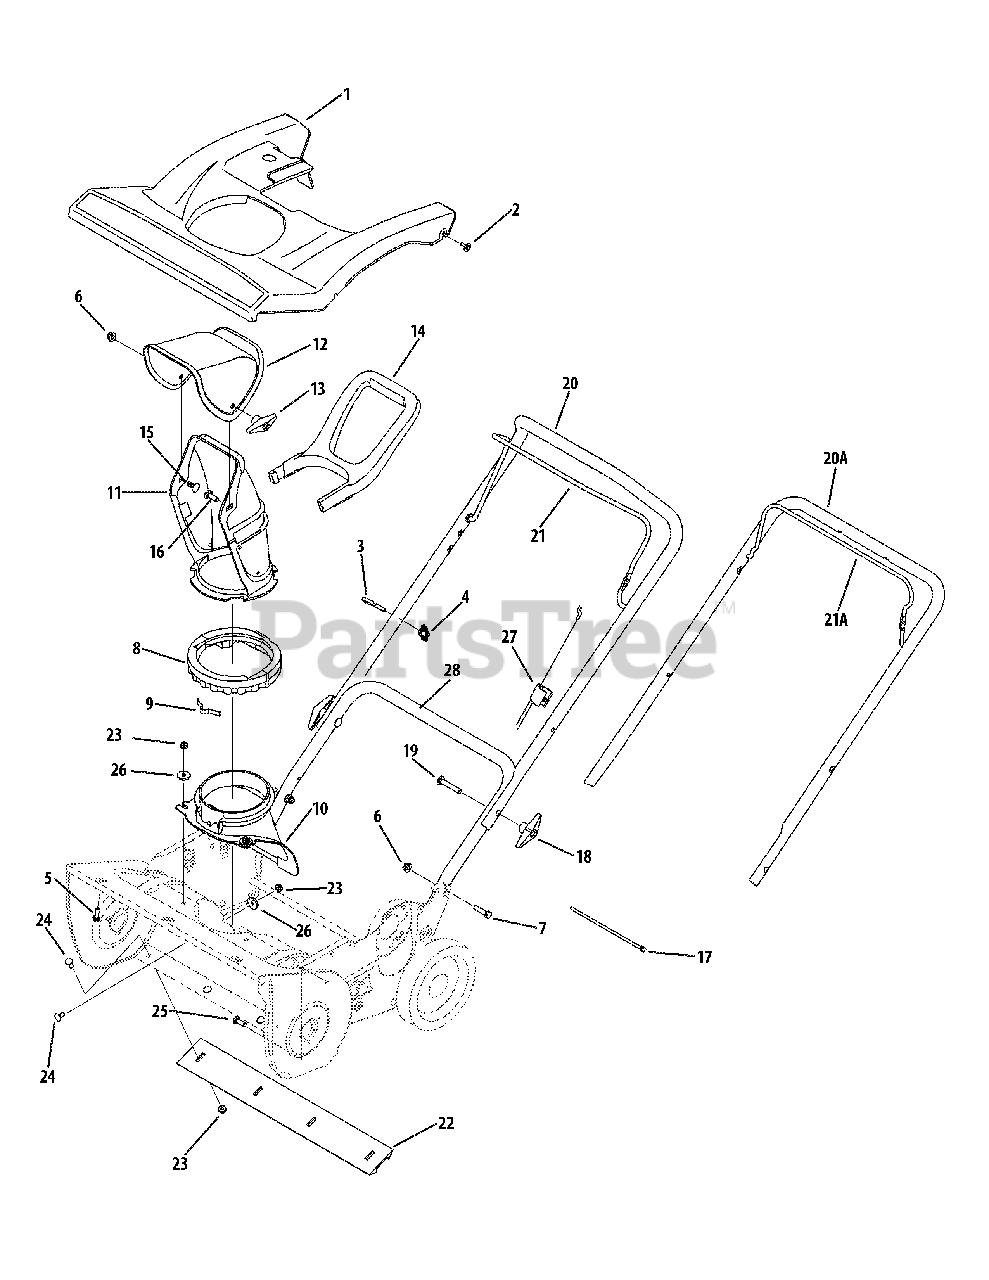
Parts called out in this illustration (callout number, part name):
1	Shroud
2	Hex Washer Screw, 10-16 x .625
3	Eye Bolt, 1/4-20
4	Knob Handle
5	Hex Washer Screw, 1/4-15 x .750
6	Flange Lock Nut, 5/16-18
7	Hex Screw, 5/16-18 x 1.25
8	Lower Chute Ring
9	Chute Adjustment Spring
10	Chute Adapter
11	Lower Chute, 5" Diameter
12	Upper Chute
13	Wing Knob
14	Chute Handle
15	Carriage Bolt, 5/16-18 x .750
16	Carriage Bolt, 5/16-18 x 1.00
17	Cable Tie, 3/16 x .05 x 7.4
18	Wing Nut
19	Carriage Screw, 5/16-18 x 2.00
20	Gullwing Handle
21	Gullwing Control Bail
21A	Control Bail
22	Shave Plate, 21"
23	Flange Lock Nut, 1/4-20
24	Carriage Screw, 1/4-20 x .62
25	Hex Screw, 5/16-18 x .75
26	Flat Washer, .265 x .938 x .120
27	Clutch Cable
